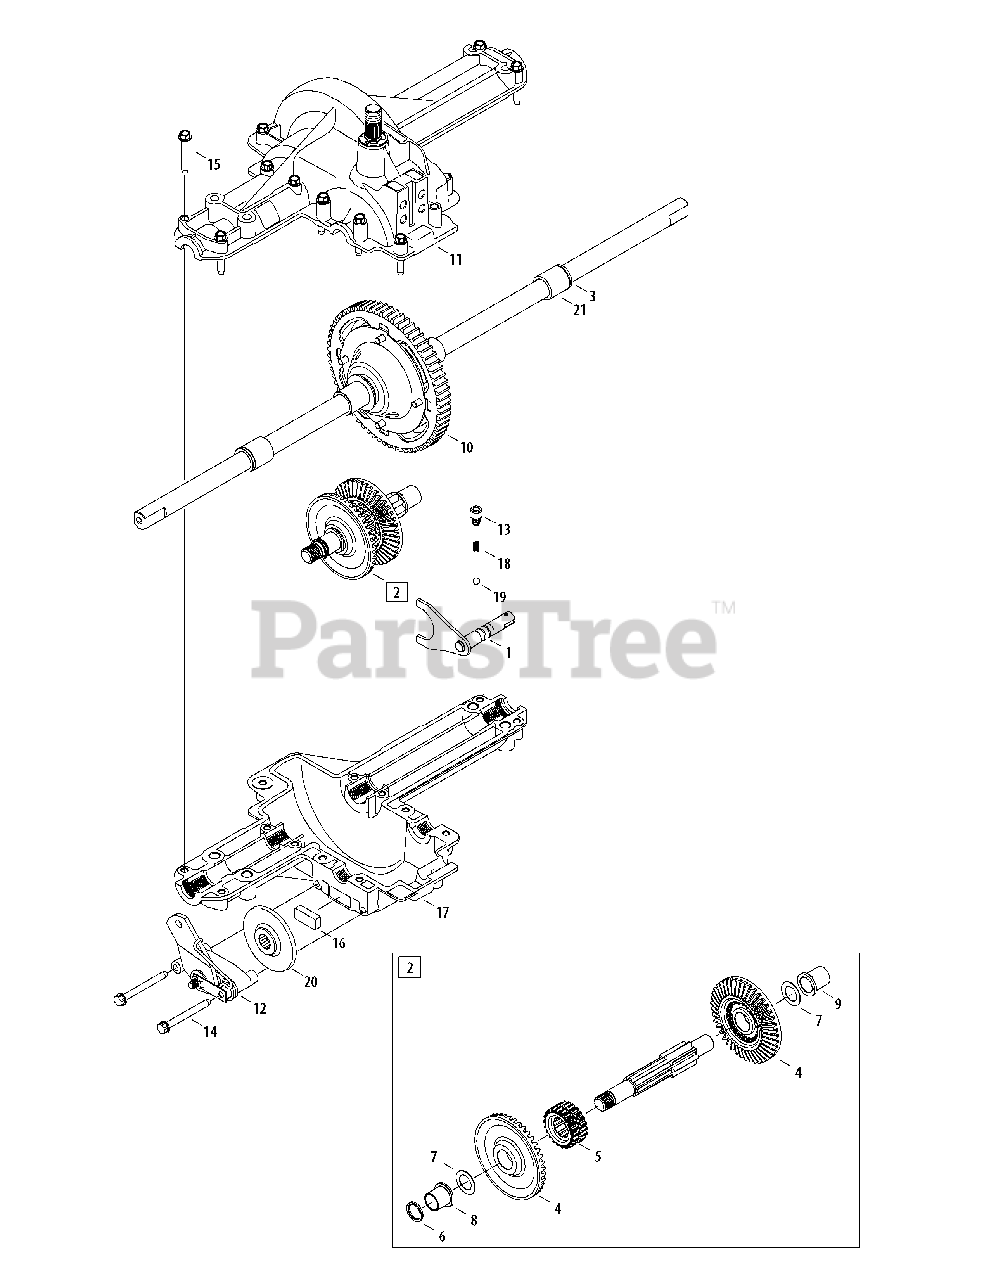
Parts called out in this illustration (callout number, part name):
1	Detent Shaft Assembly
2	Drive Shaft Ass'y (Incl. Ref. 3-9)
4	Bevel Gear 42T
5	Single Speed Clutch Collar
6	Seal .625 x .812 x .94
7	Flat Washer 5/8 ID x 1.0 OD x .030
7	Flat Washer 5/8 ID x 1.0 OD x 0.040
7	Flat Washer 5/8 ID x 1.0 x .020
7	Flat Washer .632" ID x 1.0 OD x .035
8	Thrust Wash. 5/8" ID x 1.0" OD x .025
9	Flange Bearing 5/8 x 3/4 x 3/4
9	Flange Bearing 5/8 x 3/4 x 15/16
10	Differential Assembly
11	Upper Housing
13	S-Tap ping Screw 5/16-18 x .375
14	Hex Wash. Hd. Self-Tap Screw. 1/4-20
15	S-Tap ping Screw 1/4-10 x 1.625
17	Lower Housing
18	Compression Spring
19	Ball Detent .250 Dia.
21	Sleeve Bearing 3/4 ID x 1.0
